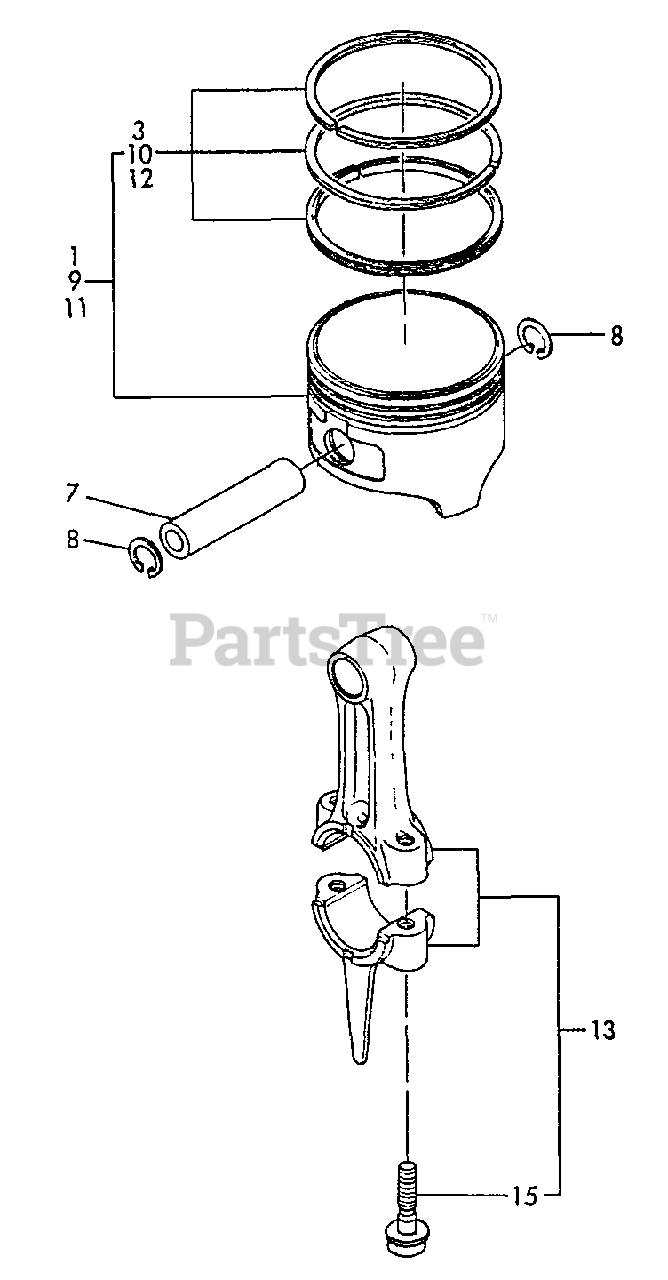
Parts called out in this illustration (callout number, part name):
1	PISTON KIT
3	RING, PISTON
7	PIN, PISTON
8	RING, RETAINING - 13
9	PISTON KIT
10	RING, PISTON
11	PISTON KIT
12	RING, PISTON
13	CONNECTING ROD ASSY
15	BOLT
